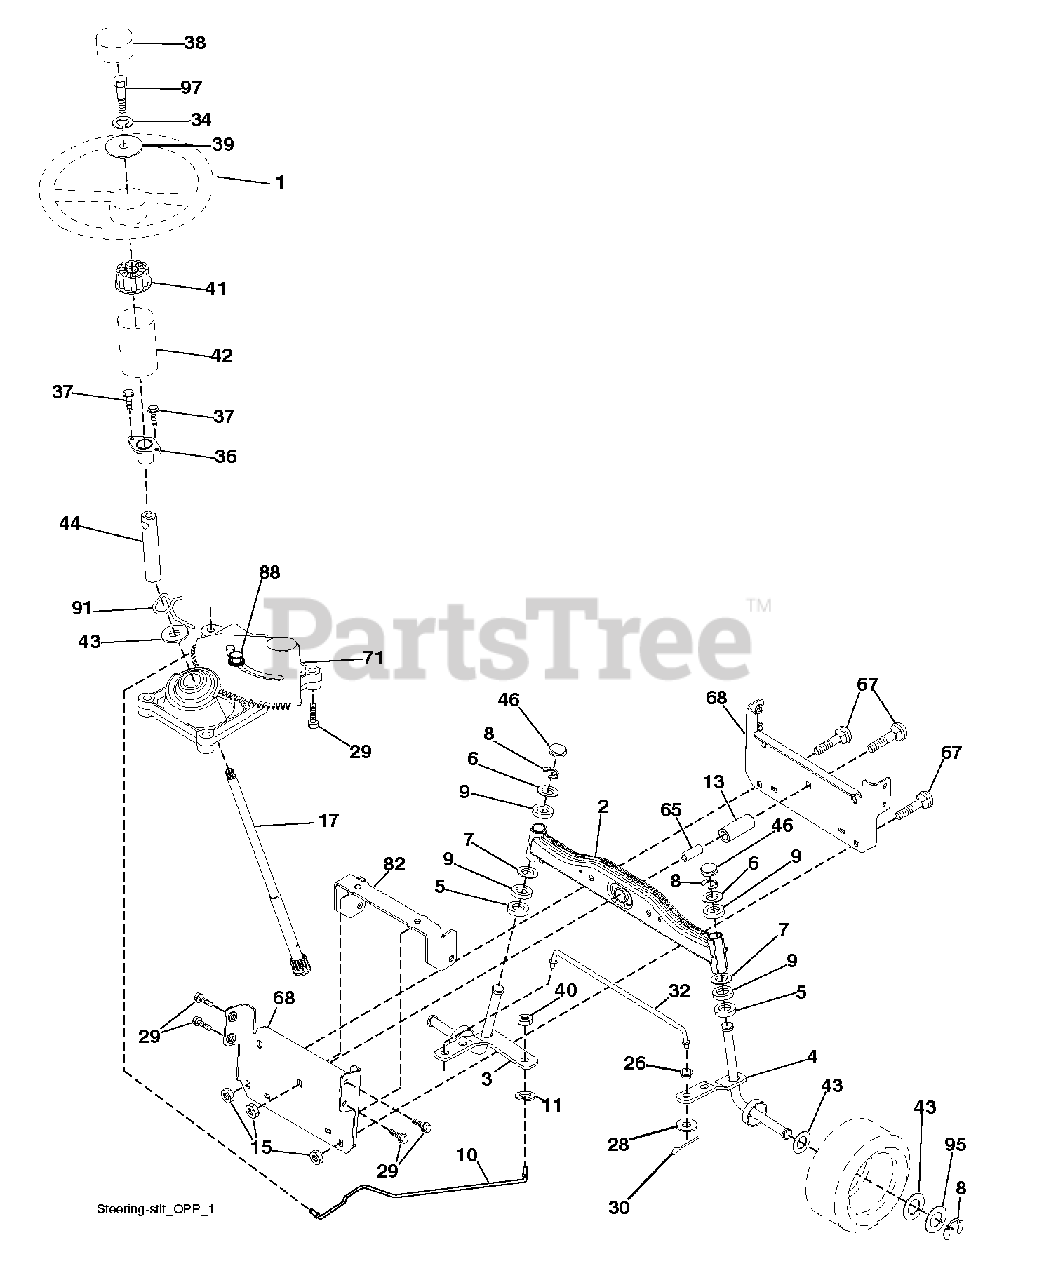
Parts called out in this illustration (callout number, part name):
1	WHEEL.STEERING.HARD.RIM.BLAC
2	AXLE HALF ASM-WELDED
3	SPINDLE.ASM.LH.15"TIRES
4	SPINDLE.ASM.RH.15"TIRES
8	RING CLIP
9	Steering Column Bearing
10	DRAGLINK.15".TIRES.2001
11	WASHER, LOCK 3/8
13	TUBE, PIVOT AXLE (2 2)
15	NUT LOCK FLG 3/8-16 UNC
26	BUSHING.DRAGLINK (2 2)
28	WASHER
29	SCREW, 3/8-16X3/4
30	COTTER PIN
32	ROD.TIE.WIRE.FORM
34	LOCKWASHER
37	SCREW.TT.#10-32X.5.3/8.FLANGE
38	INSERT, WHEEL STEERING
39	WASHER.11/32
40	NUT CROWNLOCK 3/8-24
41	ADAPTER, WHEEL STNG..
42	BOOT.STEERING.SHAFT.BLACK
44	SHAFT.EXTEN.STRG.SPLINE
46	CAP.SPINDLE.BLACK
65	SPACER.BRACE.AXLE
67	BOLT CARRIAGE
68	BRACE.AXLE.15"TIRES
71	STEERING ASM
82	BRACKET.SUSP.CHASSIS.FRONT.15
88	BOLT, SHOULDER 7/16-20
91	CLIP.STEERING
95	WASHER.HARDENED
97	BOLT 5/16-18 X 4 W/PATCH
